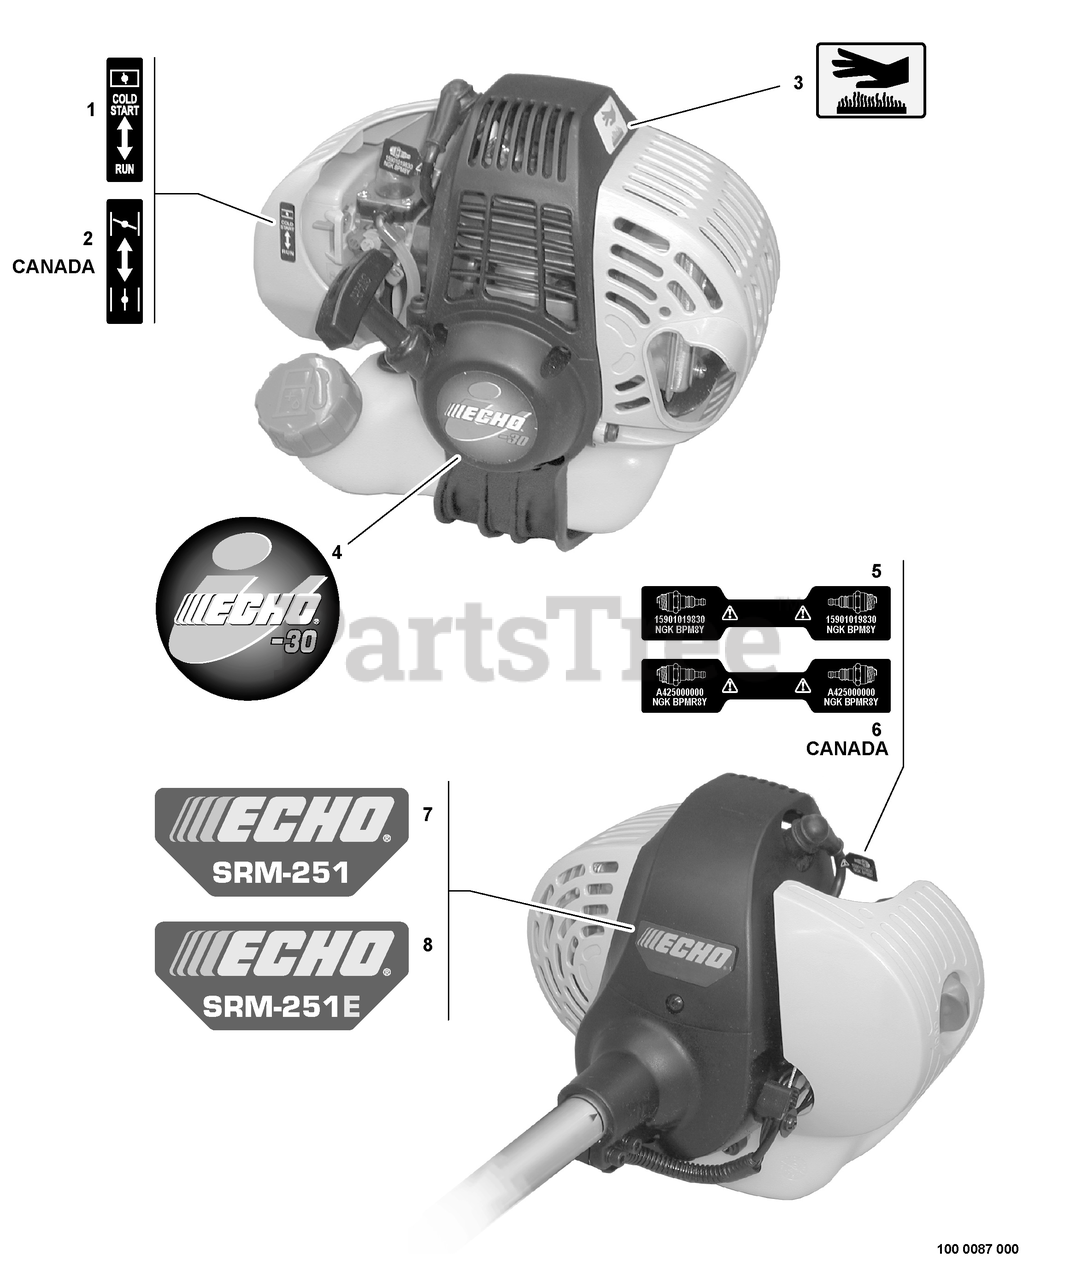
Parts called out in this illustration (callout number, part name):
1	LABEL - CHOKE
2	LABEL - CHOKE
3	LABEL - HOT SURFACE
4	LABEL - ECHO -- i-30
5	LABEL - SPARK PLUG -- BPM-8Y
6	LABEL - SPARK PLUG -- BPMR-8Y
7	LABEL - MODEL GT-251
8	LABEL - MODEL GT-251E
